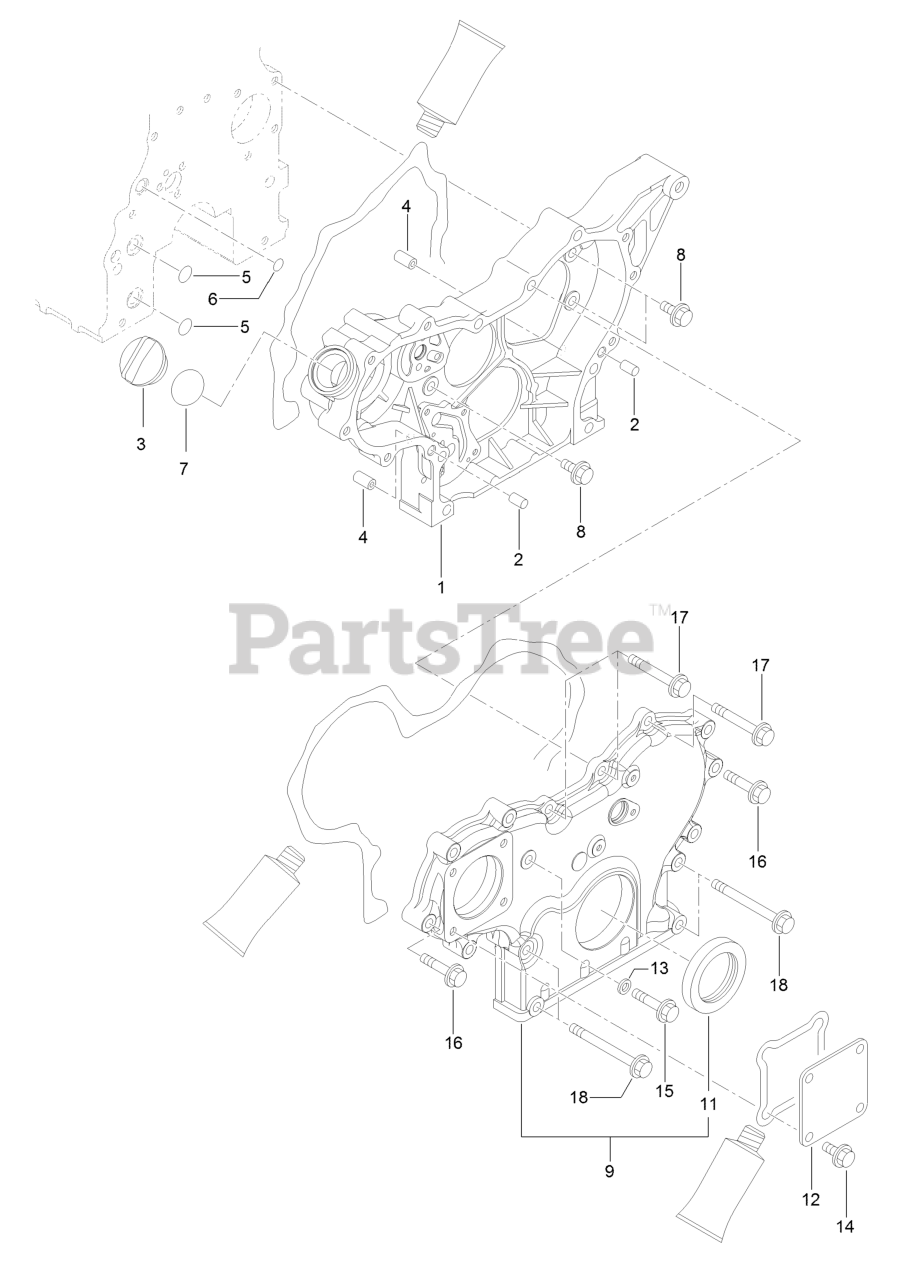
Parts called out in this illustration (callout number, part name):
1	Case-Gear
3	Cover-Filler
8	Bolt
9	Gearcase Cover ASM
11	Seal-Oil
13	Washer-Seal
14	Bolt
